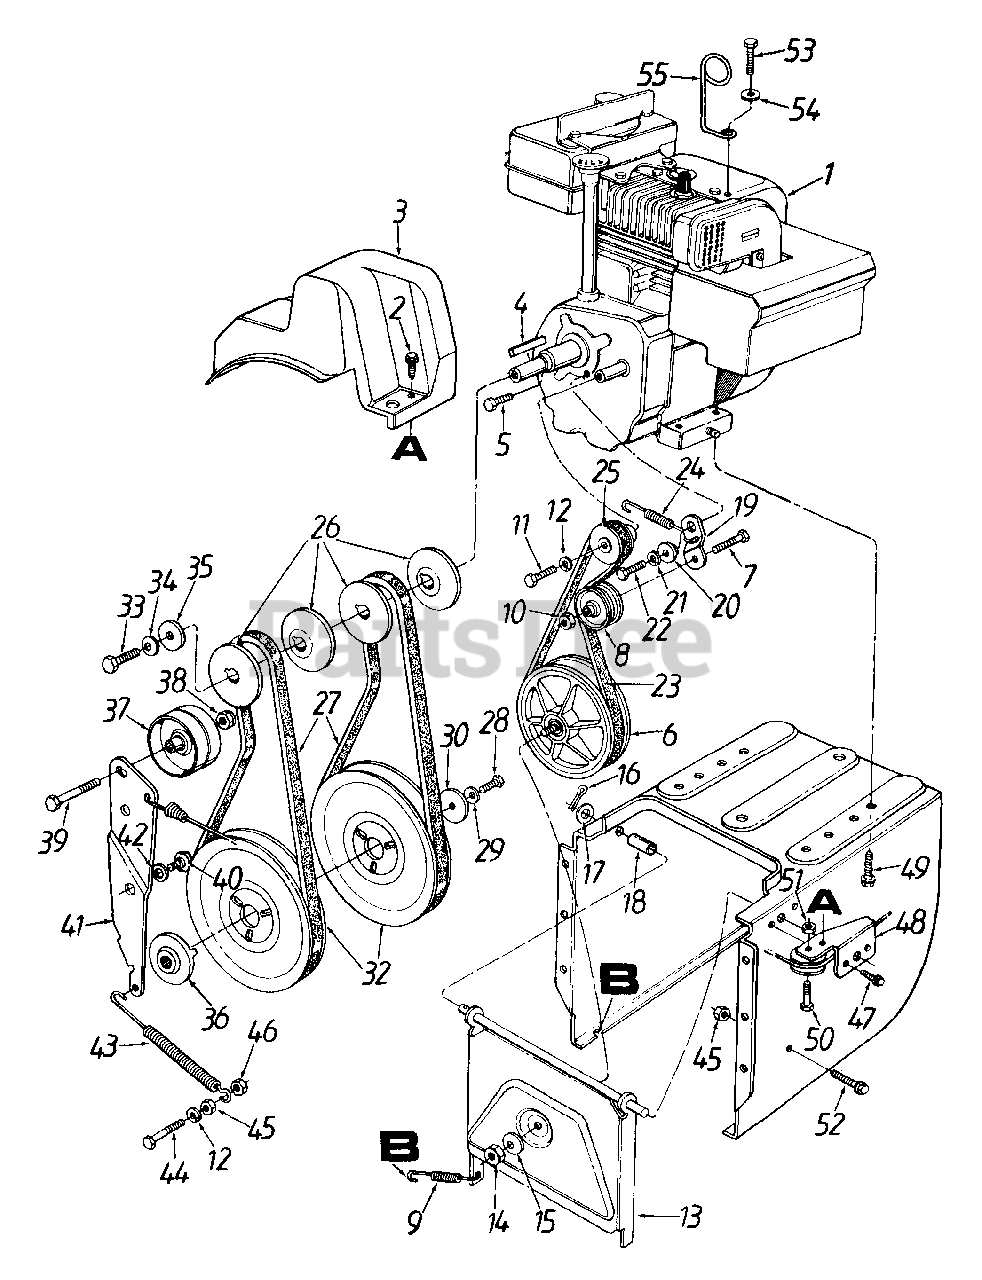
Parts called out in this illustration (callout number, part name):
1	Engine
2	Hex Wash. Hd. TT-Tap Scr. 1/4-20 x .5" Lg.
4	Sq.-Key 3/16 x 1.5" Lg.
5	Hex Patch Bolt 5/16-24 x 1" Lg. (Gr. 5)
6	Friction Wheel Disc Ass'y.
7	Hex Bolt 3/8-16 x 1.25" Lg.
8	Fl-Idler 2.12" O.D.
9	Ext. Spring 2.5" Lg.
10	Hex Top L-Nut 3/8-16 Thd.
11	Hex Bolt 1/4-28 x .5" Lg.
12	L-Wash. 1/4" I.D.
15	Bell-Wash. .38" I.D. x .88" O.D.
16	Cotter Pin 1/8" x .75" Lg.
17	Fl-Wash. .531" I.D. x .93" O.D.
18	Spacer.508" I.D. x .75" O.D.
19	Drive Clutch Idler Bracket
20	Shld. Spacer .5" Dia. x .27" Lg.
22	Hex Wash. Hd. Tap Scr. 5/16-18 x .62" Lg.
23	"V"-Belt
24	Extension Spring
25	2" Dia. Pulley
26	3/8 "V"-Pulley Half
27	"V"-Belt
28	Hex Cap L-Bolt 5/16-24 x .75" Lg.
29	Bell-Wash. .345" I.D. x .88" O.D.
30	Fl-Wash. .34" I.D. x 1.5" O.D.
32	Auger Pulley
33	Hex Bolt 3/8-24 x .88" Lg.
34	Bell-Wash. .39" I.D. x 1.13" O.D.
35	Fl-Wash. .406" I.D. x 1.25" O.D.
36	Adapter Pulley
37	Fl-Idler 2.75" O.D.
38	Hex Ins. L-Nut 3/8-24 Thd.
39	Hex Bolt 3/8-24 x 1.5" Lg. (Gr. 5)
40	Shld. Bolt .625" Dia. x .170" Lg.
42	Wave Wash. .66" I.D. x .88"
43	Ext. Spring 3.6" Lg.
44	Hex Bolt 1/4-20 x .75" Lg. (Gr. 5)
45	Hex Nut 1/4-20 Thd.
46	Hex L-Nut 1/4-20 Thd.
47	Torx Mach. AB-Tap Scr. 1/4 x .62" Lg.
50	Shld. Bolt 5/16" Dia. x .35" Lg.
51	Hex Jam Nut 1/4-20 Thd.
52	Hex Wash. Hd. TT-Tap Scr. 1/4-20 x 1" Lg.
53	Hex Wash. Hd. Tap Scr. 5/16-18 x 1" Lg.
54	Fl-Wash. .349" I.D. x .879" O.D.
55	Cable Control Wire
